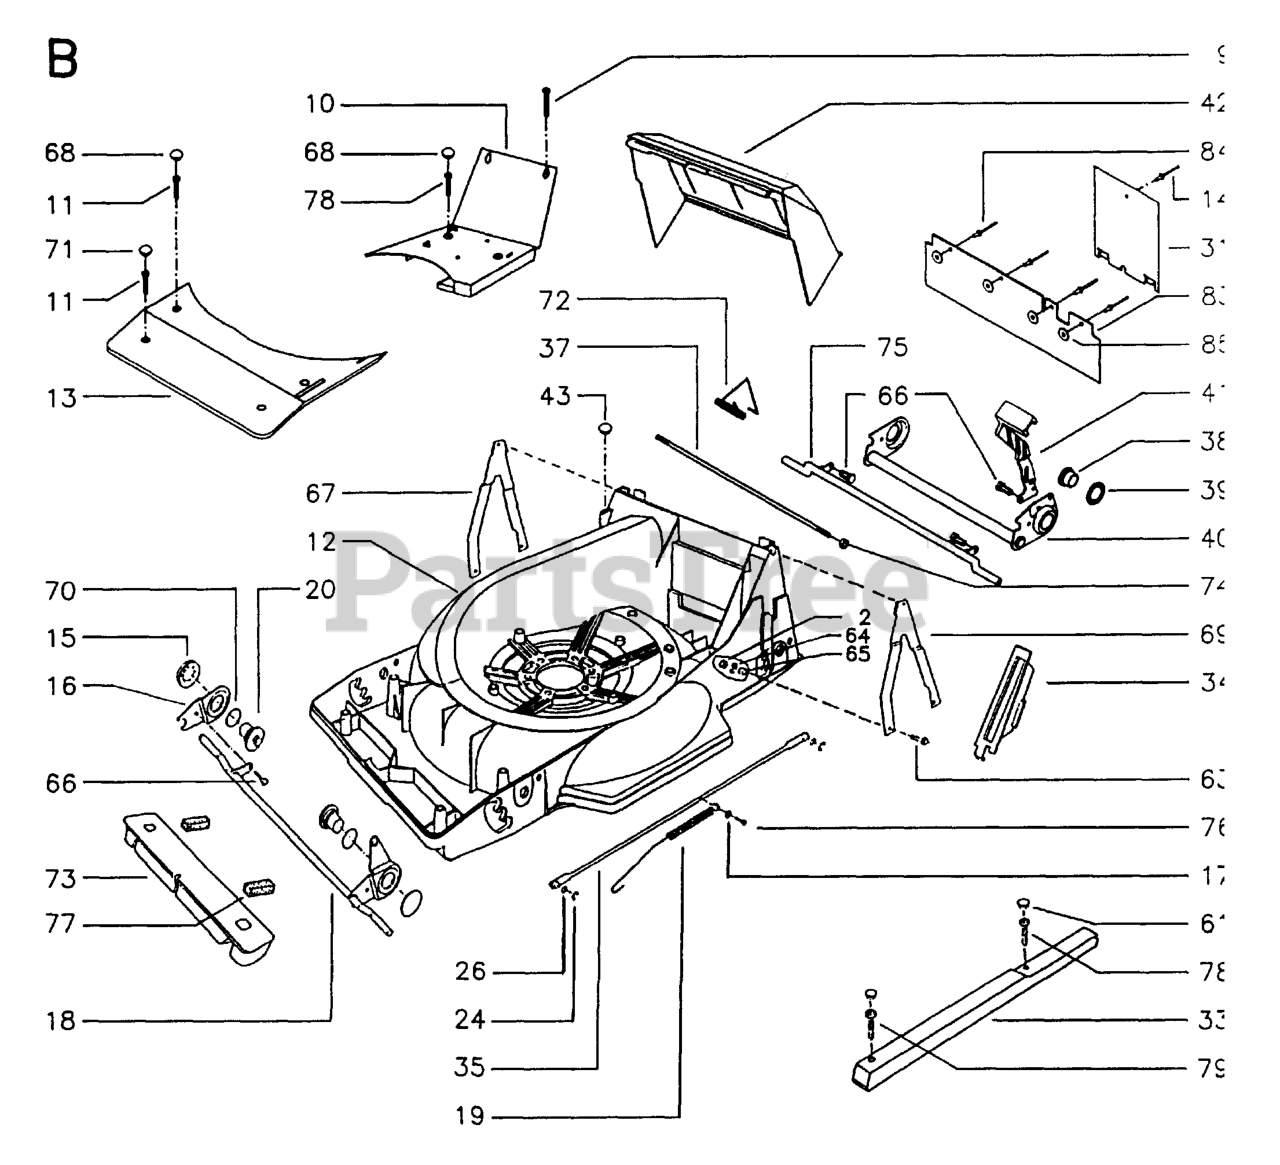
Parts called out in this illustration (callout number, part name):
2	LOCKNUT M8
10	BRACKET 48S
34	HEIGHT ADJ. COVER
37	REPL BY 516 49 96-01
39	LOCK WASHER
76	SCREW TAPTITE
83	SPLASH GUARD
84	REPL BY 516 92 38-00
